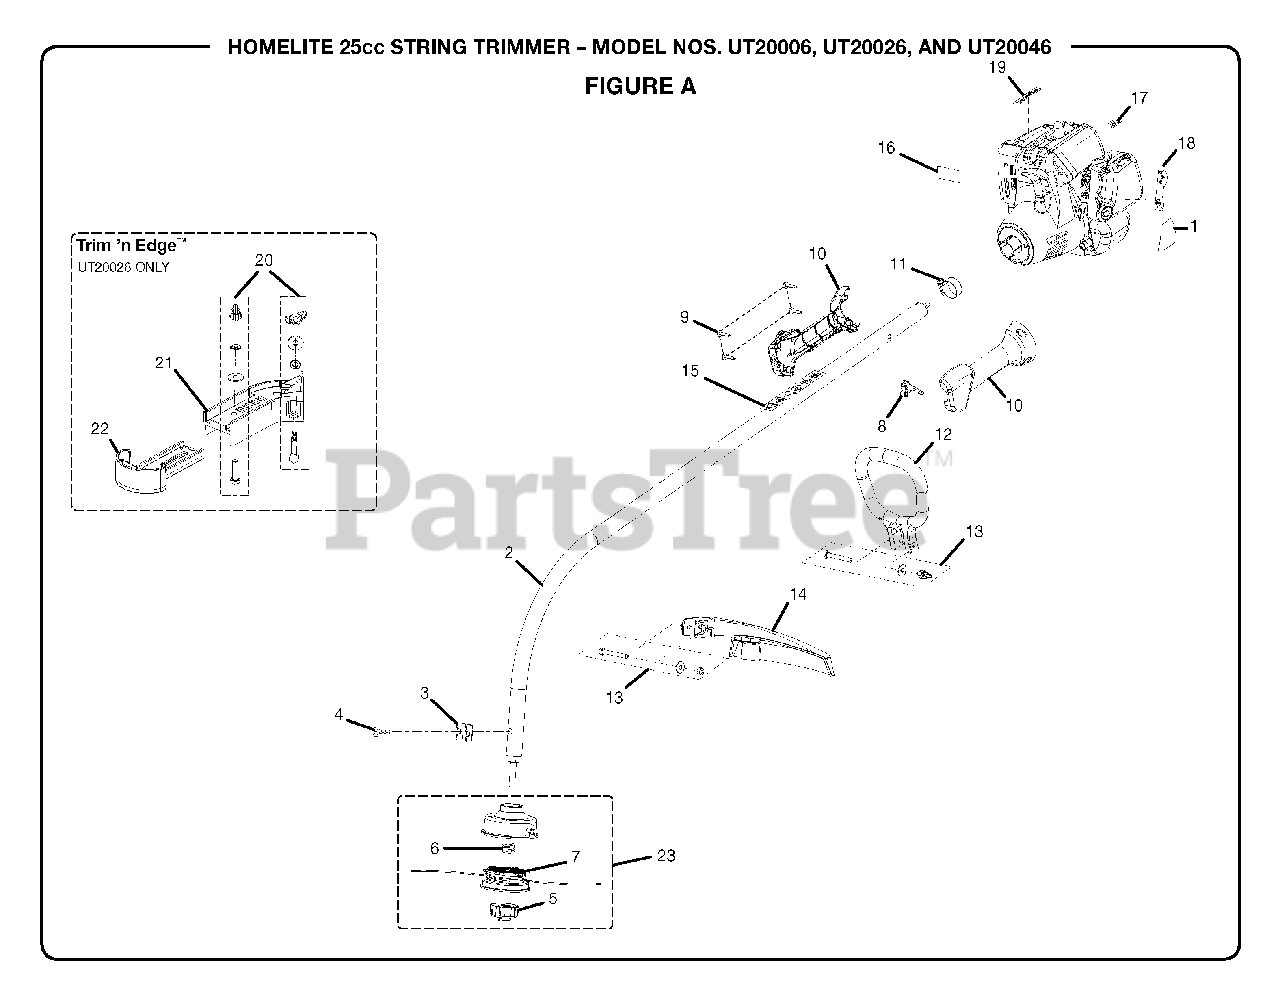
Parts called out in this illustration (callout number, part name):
1	STARTING INSTRUCTION DECAL
2	CURVED SHAFT ASSEMBLY
3	CLAMP
4	SCREW (10-32 x 3/8 in.)
5	SPOOL RETAINER (RH)
6	COMPRESSION SPRING
7	SPOOL W/LINE
9	SCREW (10-14 x 7/8 in. TRUSS HD.)
10	HANDLE GRIP ASSEMBLY
11	BOOM CLAMP
12	FRONT HANDLE
13	FASTENER PARTS KIT
14	GRASS DEFLECTOR ASSEMBLY
15	DECAL, WARNING/STARTING BOOM
16	DECAL, TRIMLITE LOGO
17	DECAL, PRIMER
18	DECAL, CHOKE
19	DECAL, HOMELITE
20	FASTENER PARTS KIT
21	EDGER BASE
22	EDGER GUIDE
23	COMPLETE STRING HEAD (.080 in.)
